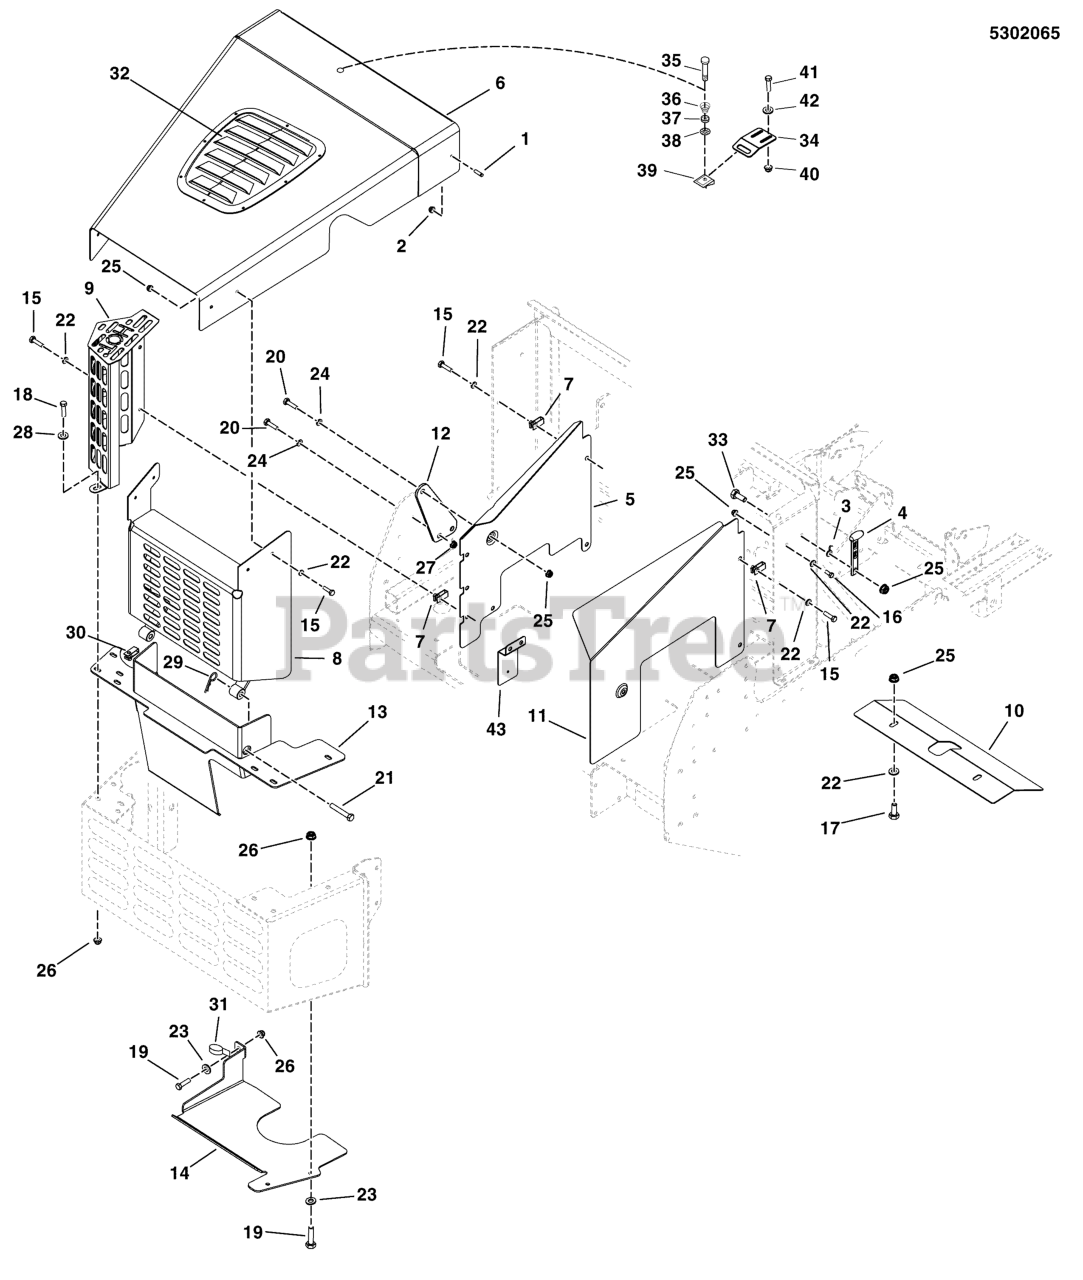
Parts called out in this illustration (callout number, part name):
1	BINDING POST #8-32X.500 INT THR BLK
2	SCREW-HEX SERR FLNG LK #8-32X0.375 YEL
3	HOOK-.125DIA WIRE GR CAT STRAP YELLOW
4	STRAP,HOOD,BLACK RUBBER
5	COVER,SIDE, LH - RED
6	WELD, HOOD - RED
6	WELD, HOOD, IS2500 - RED
7	BODY CLIP, 1/4-20 X 1/2 DEEP
8	WELD, REAR COVER - RED
9	WELD, MUFFLER GUARD - RED
10	PLATE, SHIELD, HYDRAULIC PUMPS - RED
11	COVER, SIDE, RH - RED
12	BRACE, SIDE COVER, S175X - RED
13	WELD, GUARD, PTO BELT - RED
14	GUARD, DECK BELT
15	BOLT, 1/4-20 X 3/4 GD5 YZ
16	BOLT, 1/4-20 X 1" GD5 CZ
17	BOLT, 1/4-20 X 1-1/4, GD5
18	BOLT, 5/16-18 X 3/4 GD5
19	BOLT, 5/16-18 X 1 GD5
20	BOLT, 3/8-16 X 1" GD5 CZ
21	CLEVIS PIN, 3/8 X 2
22	WASHER, 1/4 SAE
23	WASHER, 5/16" SAE
24	WASHER, 3/8 SAE
25	NUT, 1/4-20 HEX NYLOCK FLANGE
26	NUT, 5/16-18 HEX NYLOCK FLANGE
27	NUT, 3/8-16 HEX NYLOCK FLANGE
28	WASHER, 5/16 GD.9 FLAT
29	PIN, HAIR, .0585 X 1-1/8, 1/4 EYE, YZ
30	BODY CLIP, 5/16-18 -1/4 MATERIAL
31	CLAMP, HOSE, 1.000 DIA.
32	SCOOP, HOOD, OUTFRONT MOWER
33	BOLT,1/4-20X0.750,GR5,STD NECK,SQ,ZC/CL
34	PLATE, MOUNT, HOOD FASTENER - RED
35	DZUS, 1/4 TURN FASTENER, D8X29MM
36	DZUS, EJECTOR SPRING
37	DZUS, CUPPED WASHER
38	DZUS, RECEPTACLE, CLIP-ON, D8
39	DZUS, RETAINER, PUSH-ON, SS
40	NUT, #10-24 HEX NYLON LOCK
41	SCREW, #10-24 X 3/4 ROUND PHILLIPS
42	WASHER, #10 SAE
43	MOUNT, MAXI FUSE
